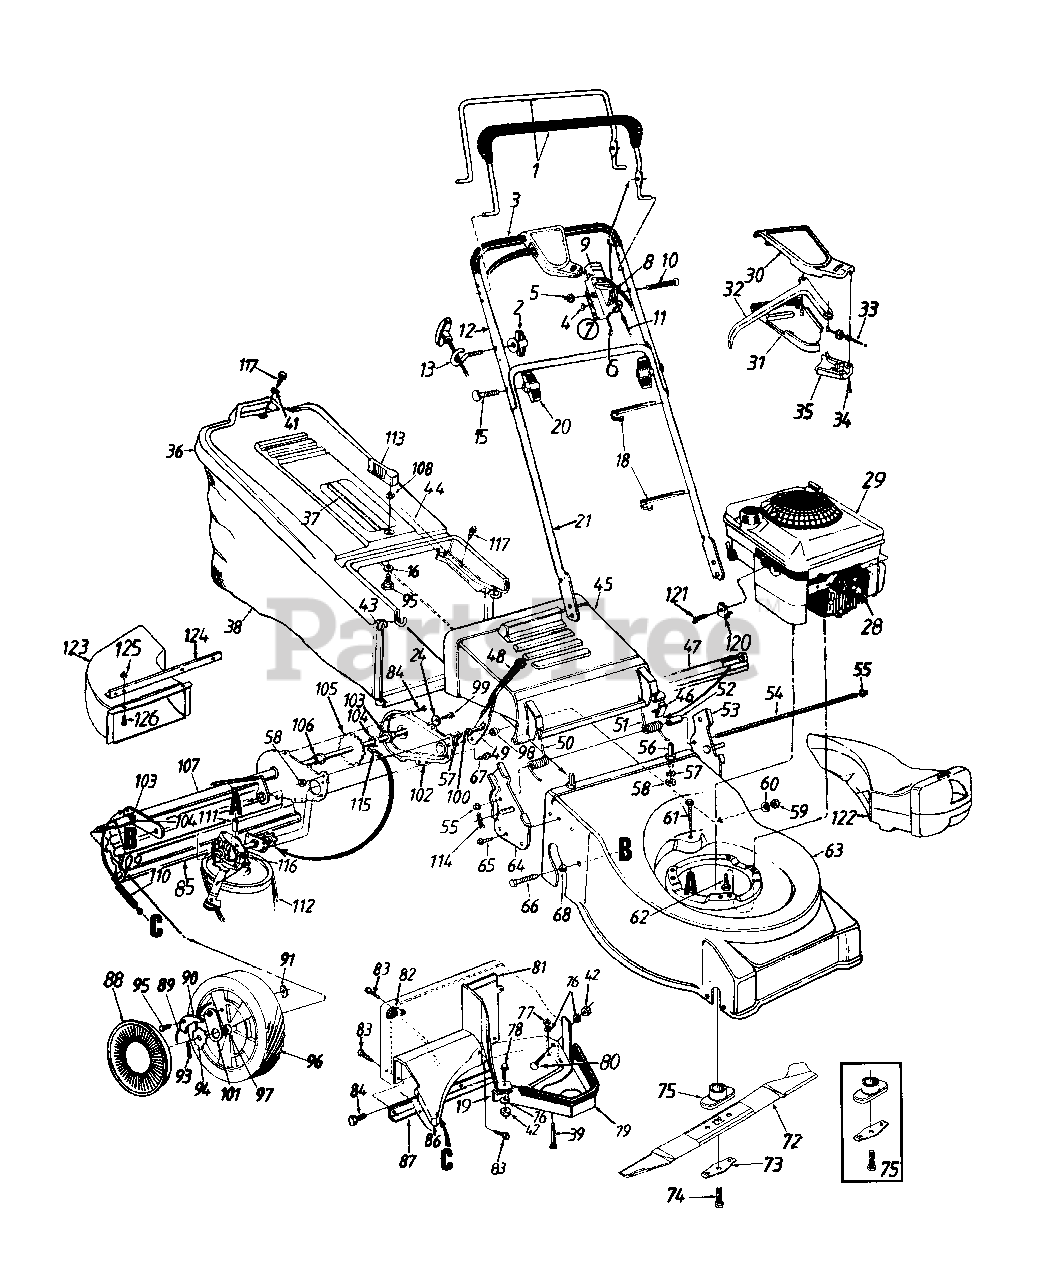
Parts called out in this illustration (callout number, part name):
2	Handle Knob 1/4-20 Thd.
3	Foam Grip
4	Spr. Wash. .66" I.D.
5	Hex L-Nut 1/4-20 Thd.
6	Throttle Cable-55"
7	Throttle Box Comp.
8	Throttle Lever
9	Throttle Body
10	Oval C-Sunk Scr.
11	Control Cable-40.5"
13	Rope Guide
15	Curved Hd. Bolt 5/16-18 x 2"
16	Bowed Washer
18	Cable Tie
19	Stop Brkt.
20	Hand Knob
24	Bell-Wash. .265" I.D. x .75"
28	Spark Plug Boot
29	Engine
30	Control Cover Half-Upper
31	Control Cover Half-Lower
32	Control Lever
33	Drive Cable-51" Lg.
34	Flat C-Sunk Hd. Tap Scr.#10 x .75" Lg.
35	Cable Mtg. Cap
36	Hardtop Bag Cover
37	Hardtop Handle
38	Grass Bag
39	Truss Mach. Scr. 1/4-20 x 1.0" Lg.
41	Fl-Wash. .281" I.D. x .62"
42	Hex Nut 1/4-20 Thd.
44	Rear Catcher Frame
45	Chute Deflector
46	Deflector Plug
47	Seal-Extrusion
49	Spring Lever
50	Torsion Spring-R.H.
51	Torsion Spring-L.H.
52	Spacer .255" I.D.
55	Cap Speed Nut
56	Shld. Pin 3/8-24 x 1.43" Lg.
58	Hex Jam Nut 3/8-24 Thd.
59	Hex L-Nut 3/8-24 Thd.
60	Bell-Wash. .38" I.D. x .88"
61	Hex Tap Scr. 1/4-20 x 1.5" Lg.
62	Hex Scr. 3/8-16 x 1" Lg.
63	21" Deck Ass'y.
66	Hex Tap Scr. 3/8-16 x .75" Lg.
67	Hex Tap Scr. 1/4-20 x .5" Lg.
68	Spacer .383" I.D.
72	21" Mulching Blade
73	Blade Bell Support
74	Hex Bolt 3/8-24 x 1.5" Lg.
75	Blade Adapter Kit
76	L-Wash. 1/4" I.D.
77	Hex Jam Nut 1/4-20 Thd.
78	Pan Head Mach. Scr. 1/4-20 x 1.0
79	Ext. Baffle
80	Carr. Bolt 1/4-20 x .50" Lg.
83	Torx Mach. AB-Tap Scr. 1/4 x .62" Lg.
84	Hex Tap Scr. 1/4 x .38" Lg.
85	Rear Flap
88	Hub Cap
89	Plastic Spring
90	Pawl .345" I.D.-R.H.
91	Weld Top L-Nut 1/4-20 Thd.
93	Cotter Pin 1/8" Dia.
94	Ratchet Wheel 1.62" O.D.
95	Shld. Bolt .342" Dia. x .268"
98	Shld. Spacer .50" Dia.
99	Hex Bolt 1/4-20 x .62" Lg. (Gr. 5)
100	Shld. Pin 3/8-24 x 1.43" Lg.
101	Pawl Plate
104	Fl-Wash. .531" I.D. x .93"
105	Rear Axle Ass'y.
106	Hex Flange Bearing
110	Extension Spring 3.8" Lg.
111	Spacer .325" I.D.
112	V-Belt
113	Grass Catcher Locking Knob
114	Internal Cotter Pin 5/16" Dia.
115	#48 Chain .50" Pitch x 30 Links
116	Transmission Comp.(See Breakdown)
120	Cable Clamp
121	Screw Tap
122	Mulching Plug
123	Chute Deflector
125	Nut 1/4"
126	Screw
